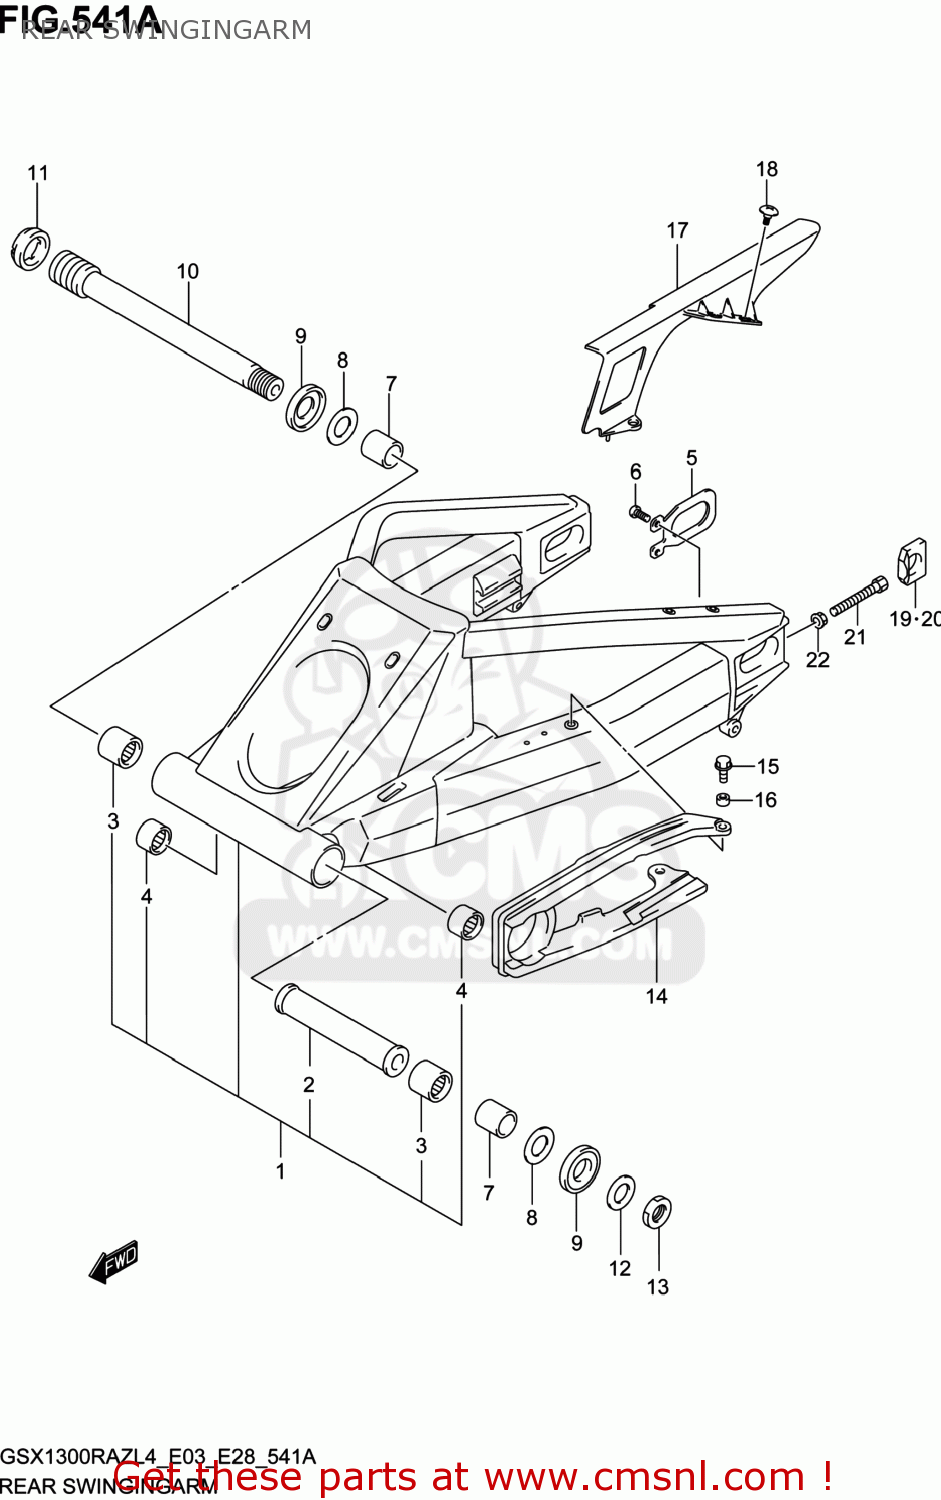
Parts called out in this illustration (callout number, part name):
1	SWINGINGARM ASSY,RR
2	SPACER,RR SWGARM PIVOT CTR
3	BEARING(30X40X25)
4	BEARING(17X24X25)
5	PLATE,RR SWING ARM BRKT
6	SCREW(6X16)
7	SPACER,RR SWGARM PIVOT BEARING
8	WASHER
9	DUST SEAL,RR SWGARM PIVOT
10	SHAFT,RR SWINGINGARM PIVOT
11	NUT,RR SWGARM PIVOT BOLT
12	WASHER(25.2X42X3.2)
13	NUT
14	BUFFER,CHAIN TOUCH DEFENSE
15	BOLT(6X20)
16	SPACER(6.5X9X5)
17	CASE,CHAIN
18	SCREW(6X16)
19	ADJUSTER,CHAIN,L
20	ADJUSTER,CHAIN,R
21	BOLT(8X50)
22	NUT
